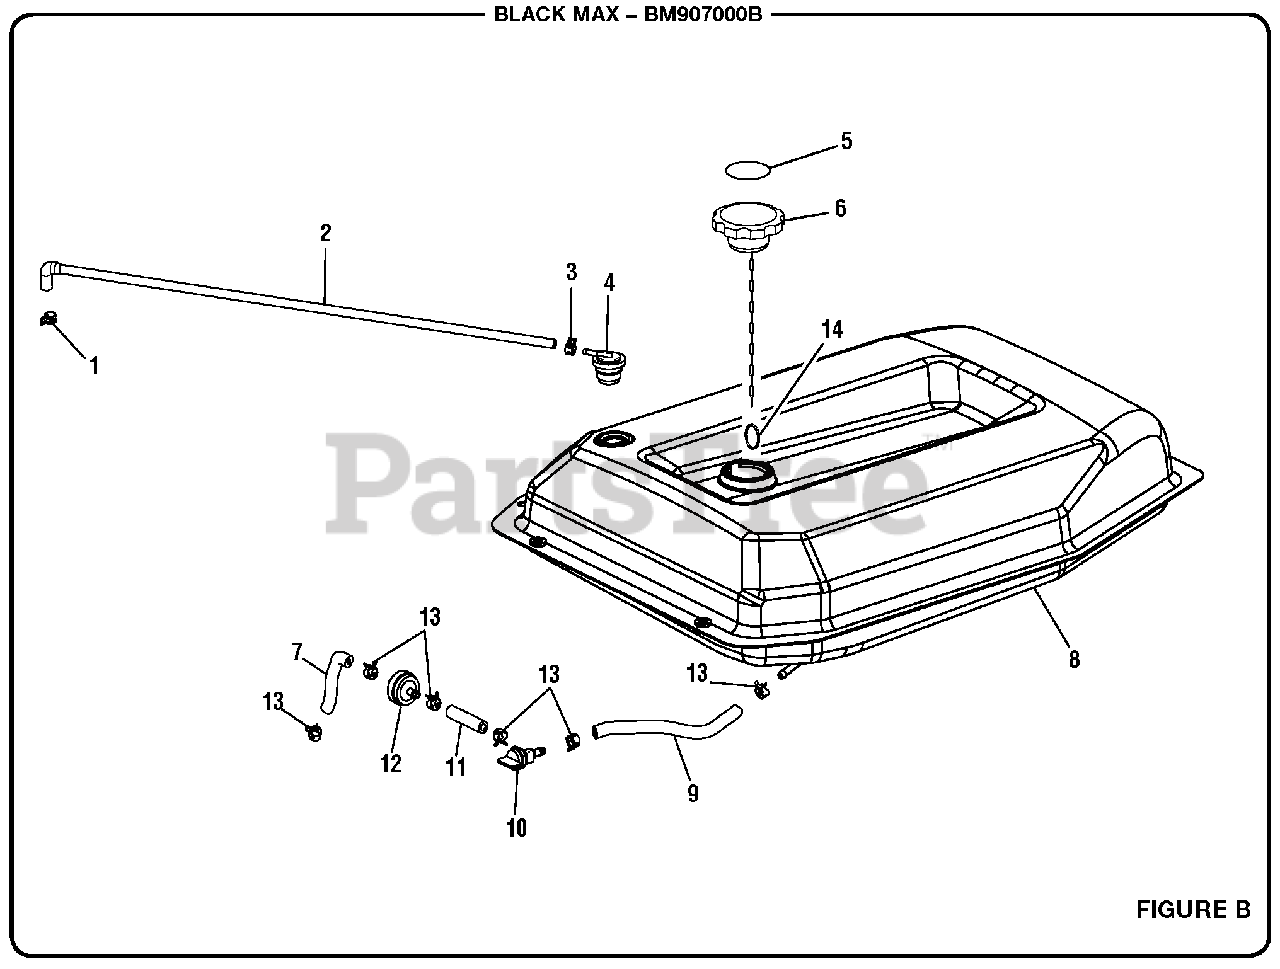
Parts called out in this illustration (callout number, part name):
1	Fuel Line Clamp (10.3 mm)
2	Vapor Hose (590 mm and 30 mm)
3	Fuel Line Clamp (3/8 in.)
4	Vapor Vent
5	Fuel Stabilizer Label
7	Fuel Hose (185 mm)
8	Fuel Tank
9	Fuel Hose (175 mm)
10	Fuel Valve
11	Fuel Hose (55 mm)
12	Fuel Filter
13	Fuel Line Clamp (1/2 in.)
14	Ring Clip
